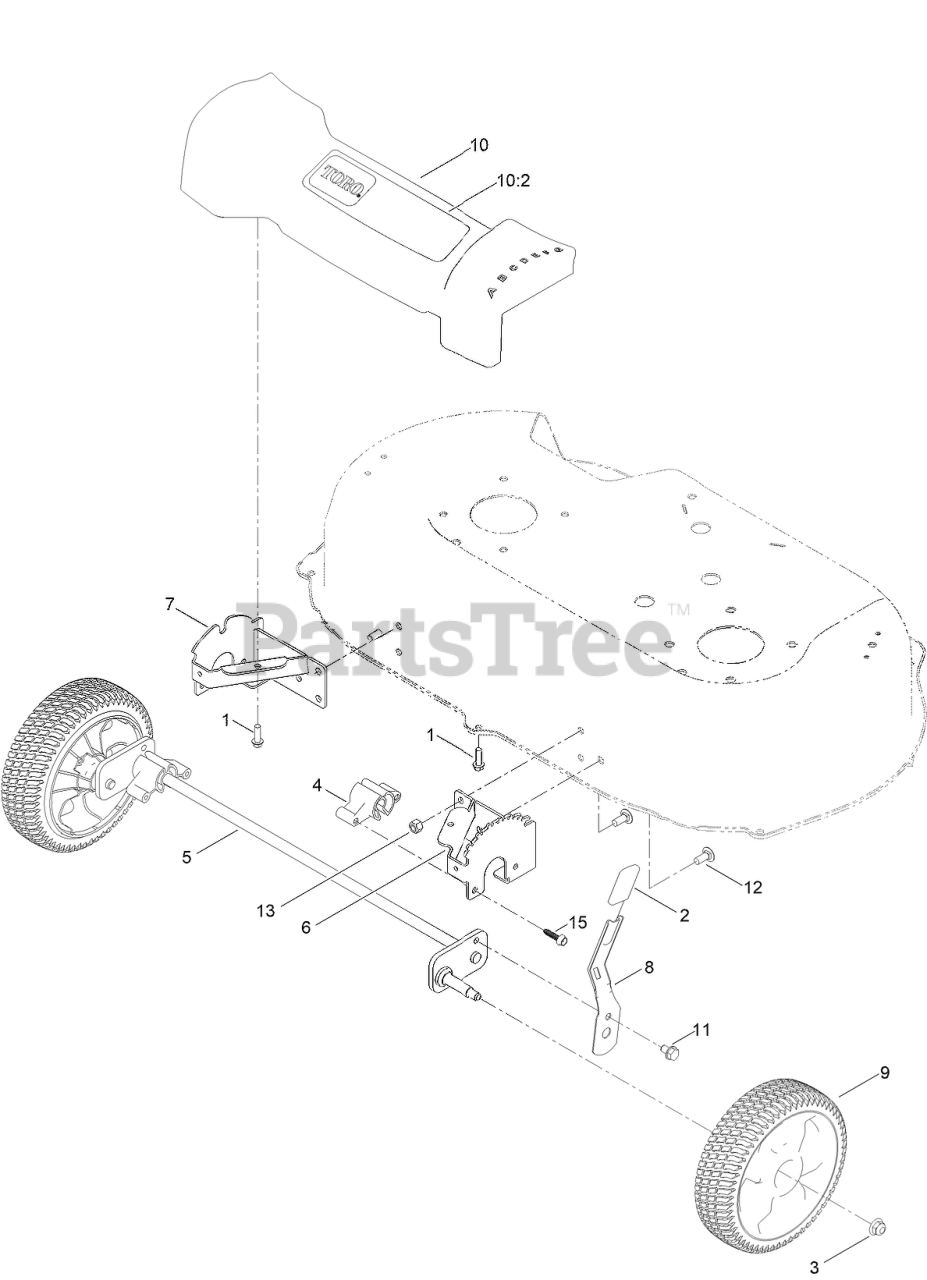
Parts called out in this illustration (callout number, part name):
1	SCREW-PLASTITE, HWH
2	GRIP-LEVER
3	NUT-HF, NI
4	BUSHING-PIVOT, FRONT
5	FRONT AXLE ASM
6	PLATE-HOC, LH
7	PLATE-HOC, RH
8	ARM-SPRING
9	8 INCH WHEEL ASM
10	FRONT COVER ASM
10:2	ARTWORK-TORO TIMEMASTER
11	SCREW-HWH, THD ROLL
12	BOLT-CARR
13	NUT-HEX
15	SCREW-FLANGE, PLASTIC
